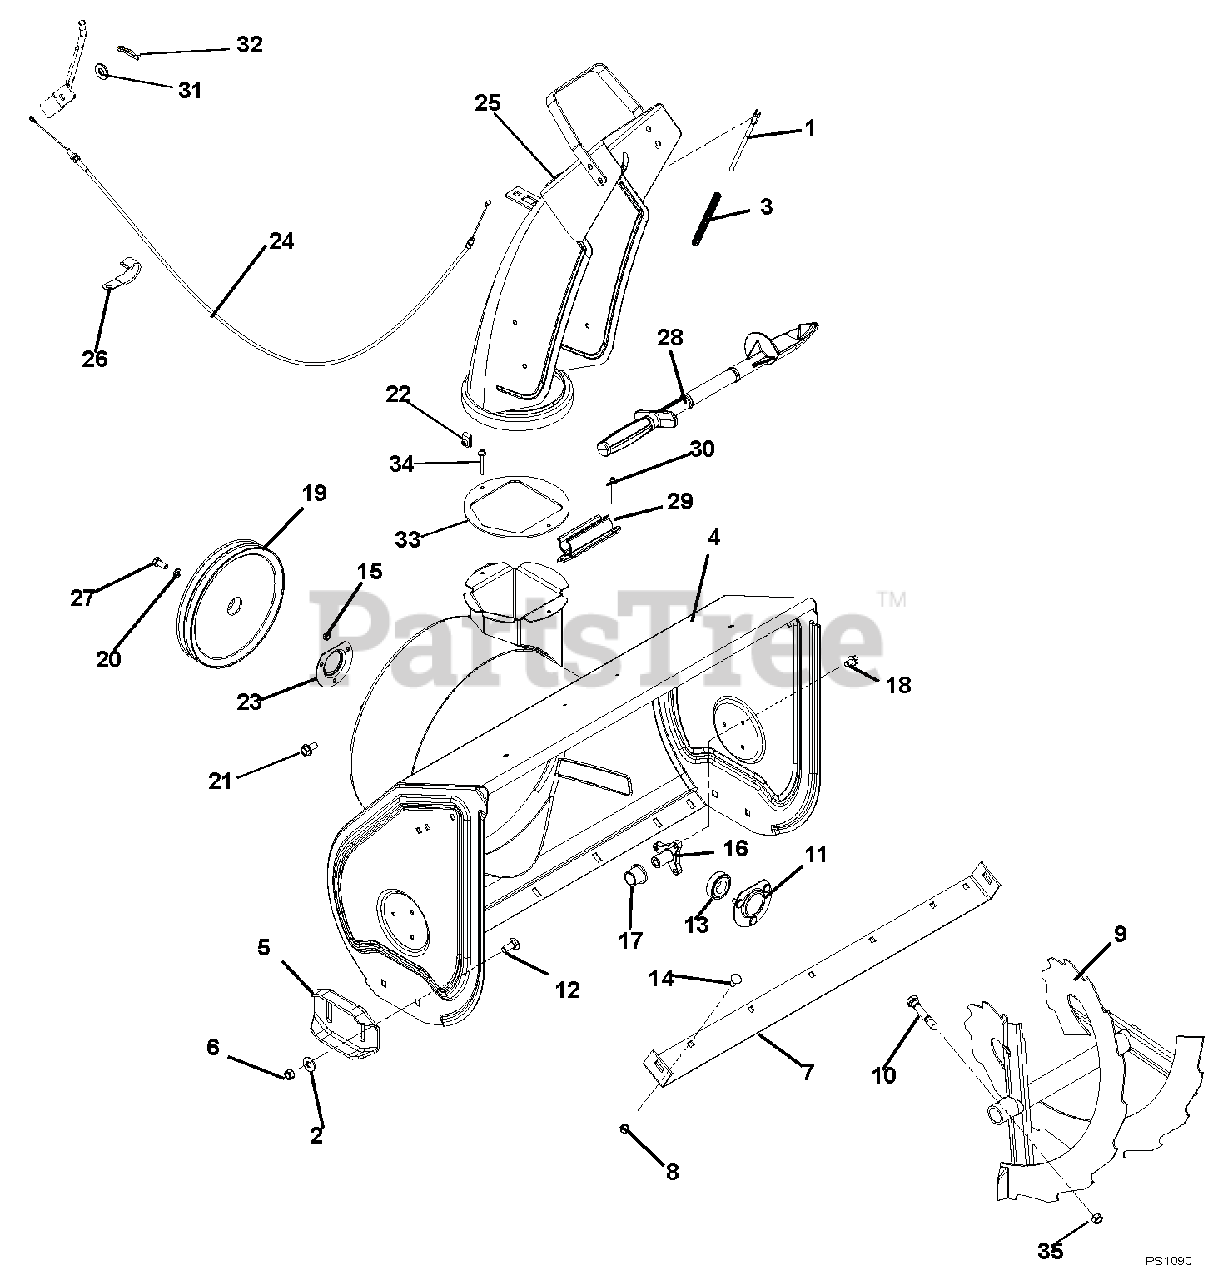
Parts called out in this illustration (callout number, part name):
1	ROD, DEFLECTOR CAP
2	@WSHR-FL-STL.438X1.00X.083 YWZ
3	SG-COMP .08X.40X6.50 14#/IN
4	HOUSING, BLOWER - 24" W/DECAL
4	HOUSING, BLOWER - 27" W/DECAL
4	HOUSING, BLOWER - 30" W/DECAL
5	SKID SHOE, REVERSIBLE - ORANGE
6	@NUT-LK-CTR .38-16 YWZC
7	BLADE, SCRAPER-24"
7	BLADE, SCRAPER-27"
7	BLADE, SCRAPER-30"
8	@NUT-LK-TOP-FLG .31-18 YWZC
9	RAKE, LEFT HAND-24" DELUXE
9	RAKE, RIGHT HAND-24" DELUXE
9	RAKE, LEFT HAND-27" DELUXE
9	RAKE, RIGHT HAND-27" DELUXE
9	RAKE, LEFT HAND-30" DELUXE
9	RAKE, RIGHT HAND-30" DELUXE
10	SHEAR BOLT SERVICE ASSEMBLY
11	BEARING FLANGE
12	@BLT-RDHDSHSQNK.38-16X1.0 G5YZ
13	BRG-BALL .876 X 1.750 X .50
14	@BLT-RHDSSQNK .31-18X.62 G5YZ
15	@NUT-LK-CTR .25-20 YWZC
16	SUPPORT, RAKE BUSHING
17	BSHG-FLG, NY.778 ID X 1.018 OD
18	@SCR-TAP .25-20X.50 HWH TR YWZ
19	PULLEY,2X4LX8.5 BOLTED
20	WSHR-LK .312X.097 HVY YWZC
21	SCR-TAP.31-18X.50 HWH TR YWZ
22	NUT-RTNR .375-16X.37
23	BEARING FLANGE
24	CABLE, DEFLECTOR
25	CHUTE, DISCHARGE-W/DEFLECTOR
25	CHUTE, DISCHARGE W/CAP & DECAL
26	J-CLAMP
27	BLT-HEX .31-24X.75 YWZC GR5
28	DEVICE, SNOW CLEAN OUT
29	MOUNT, SNOW CLEAN OUT
30	RVT-POP .187 YZ
31	@WSHR-FL-STL.281X.62X.065 YWZC
32	PIN-HAIR INT .06X.18X.77
33	BAFFLE, DISCHARGE NECK
34	RVT-POP .187 YZ
35	@NUT-LK-CTR .31-18 YWZC
